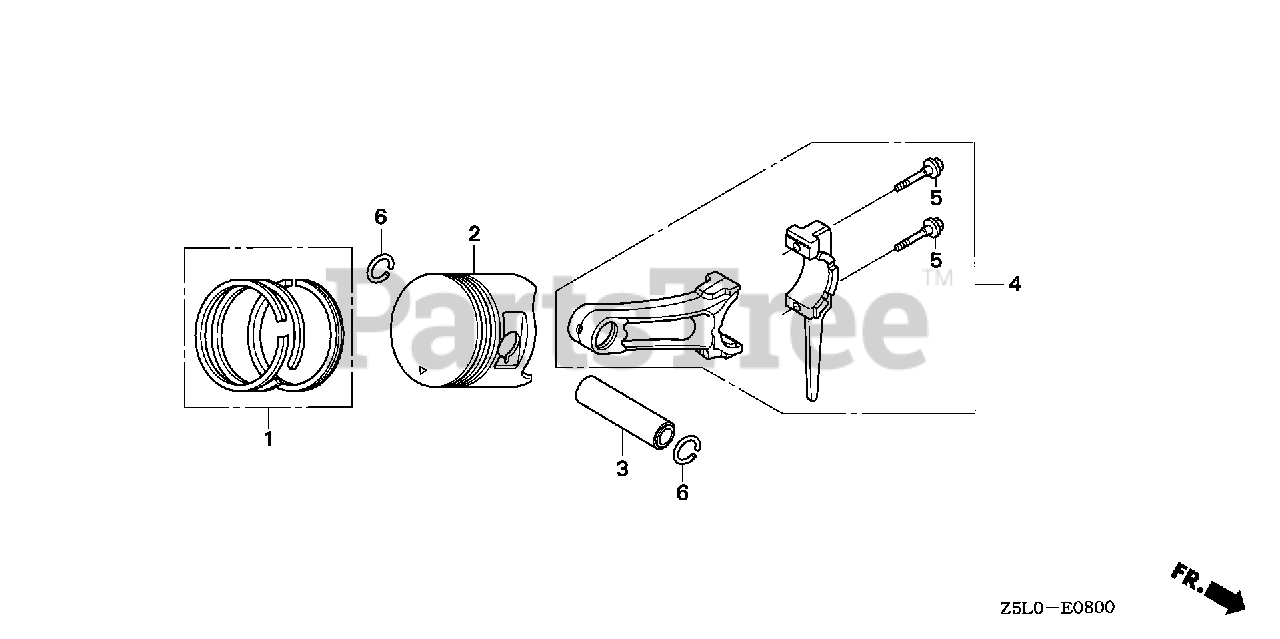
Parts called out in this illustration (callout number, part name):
1	RING SET, PISTON (STD) (NIPPON)
1	RING SET, PISTON (STD) (TPR)
1	RING SET, PISTON (0.25) (NIPPON)
1	RING SET, PISTON (0.25) (TPR)
1	RING SET, PISTON (0.50) (NIPPON)
1	RING SET, PISTON (0.50) (TPR)
1	RING SET, PISTON (0.75) (NIPPON)
1	RING SET, PISTON (0.75) (TPR)
2	PISTON (STD)
2	PISTON (0.25)
2	PISTON (0.50)
2	PISTON (0.75)
3	PIN, PISTON
4	ROD ASSY., CONNECTING (STD)
4	ROD ASSY., CONNECTING (0.25 LOWER SIZE)
5	BOLT, CONNECTING ROD
6	CLIP, PISTON PIN (20MM)
